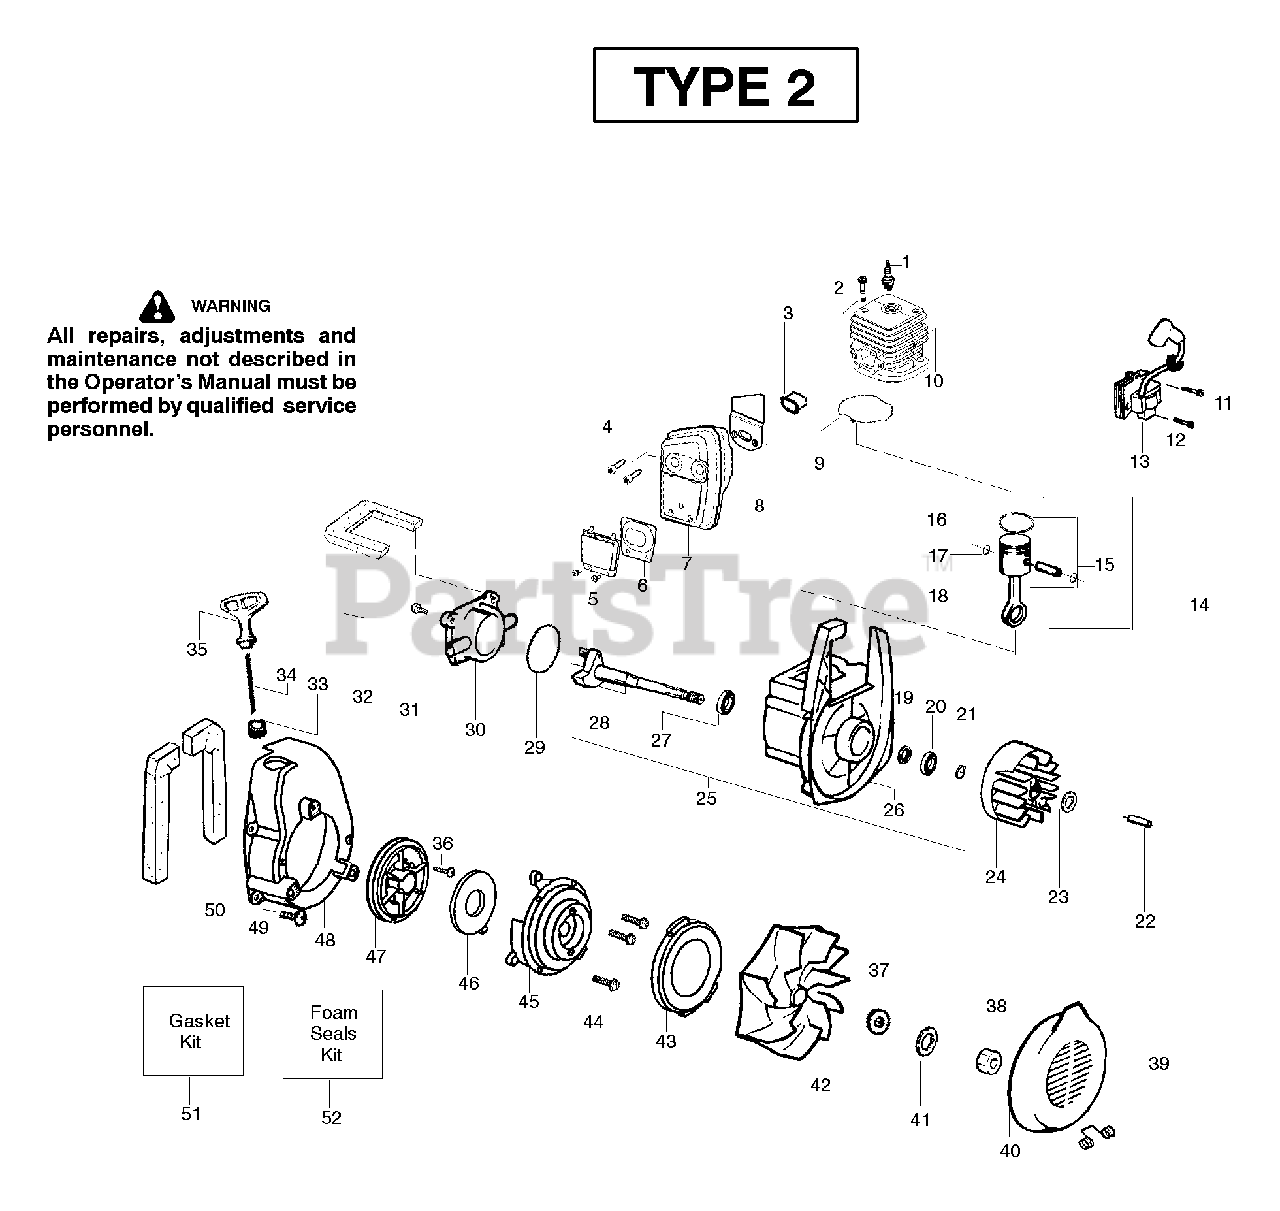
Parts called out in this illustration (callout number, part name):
1	Spark Plug (RCJ-6Y)
3	Insulator-Heat
4	Screw-Muffler-Internal
6	Kit-Spark Screen
7	Kit-Muffler
8	Gasket-Baffle (kit)
9	Gasket-Cylinder (kit)
10	Kit-Cylinder
11	Grommet-Ign. Module
12	Screw-Ignition Module
13	Ignition Module
14	Kit-Piston/Rod
15	Kit-Piston
16	Piston Ring
17	Retainer-Piston Pin
18	Assy-Connecting Rod
19	Seal-Crankcase
20	Bearing-Outer
21	Retainer Ring-C'chaft
22	Spacer-Flywheel
24	Assy-Flywheel
25	Assy-Crankcase/Crankshaft
26	Assy-Crankcase
27	Bearing-Inner
28	Assy-Crankshaft
29	O-ring-C/case (kit)
30	Cover-Crankcase
31	Screw
32	Foam-219mm (kit)
33	Eyelet-Flange
34	Kit-Rope
35	Handle-Starter
36	Screw-Rope
37	Washer-Belleville
39	Spring-Return Cover
40	Inlet Door
42	Assy-Impeller
43	Seal-Ring
45	Housing-Pulley
46	Spring-Starter
47	Kit-Starter Pulley
48	Fan Housing
49	Screw
50	Foam-182mm (kit)
51	Kit-Gasket
52	Kit-Foam Seals
